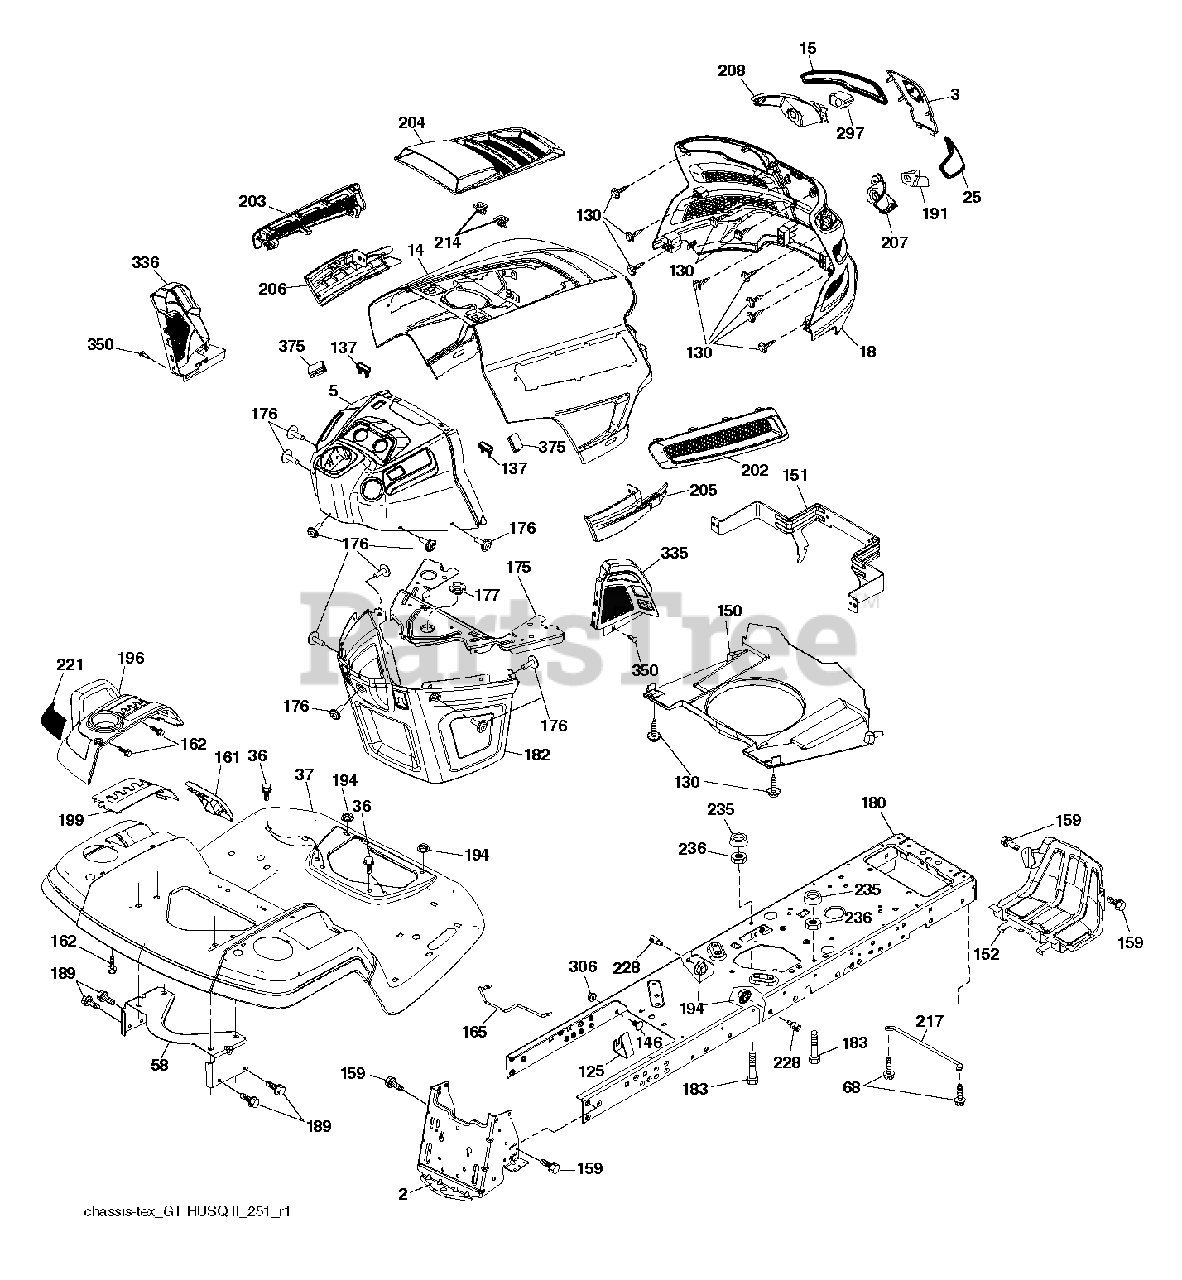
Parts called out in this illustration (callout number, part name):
2	DRAWBAR.STGT
3	APPLIQUE.SUBASM.GT.HUSQ.II
5	DASH.UPR.GT2.SRV.MIND.PTO
14	HOOD.ASM.HUSQVARNA.GT.TEX.ORAN
15	LENS.HEADLIGHT.LH.GTII.2011
18	GRILLE SUBASM.GT.II.LOW.HDLGHT
25	LENS.HEADLIGHT.RH.GTII.2011
36	SCREW 5/16"
37	FENDER.PNT.TX.GT.CH/FW/DL.HUSQ
58	BRKT.SUPPORT.FNDR/TANK
68	SCR 5/16-18 X 1/2 SELFTAP ZN
125	CLIP.FUEL.LINE
130	SCREW.#10 X 0.750.BOS
137	BUMPER DASH
146	BOLT.RDHD.SHT.SQNK.3/8-16X5/8
150	AIR.DUCT.GTV.BLACK
151	BRACKET.PIVOT.HOOD.GT.HUSQ.II
152	SHIELD.BROWNING.PNT.GT.V2
159	SCREW, 3/8-16X3/4
161	CONSOLE.WINDOW.FUEL.HUSQ.GT
162	SCREW.HI-LO.CONSOLE
165	SUPPORT.TANK.REAR.B/TE
175	PLATE.CROSSMEMBER.HUSQ
176	SCREW.#10-24X5/8.RN.QU
177	BUSHING STEERING
180	CHASSIS.LT/GT.BOLTED
182	DASH LOWER.HUSQ.PRED NO CRUISE
183	BOLT.5/16-18X1-1/4 FULL THD
189	SCREW
191	INSERT.REFLECTIVE.RH.HUSQ.GTII
194	NUT LOCK HEX FLANGE 5/16-18
196	SUBASM.CONSOLE.HUSQ.GT.DECKLFT
199	PLATE.DECK.LIFT.HUSQVARNA.GT
202	VENT.SIDE.RH.GT.HUSQ.II.
203	VENT.SIDE.LH.GT.HUSQ.II.498
204	VENT.TOP.HUSQ.GT2
205	SIDE.TRIM.RH.GT.HUSQ.II
206	SIDE.TRIM.LH.GT.HUSQ.II.GRAY
207	HEADLIGHT.CUP.BEZEL.HUS.GT2.RH
208	HEADLIGHT.CUP.BEZEL.HUS.GT2.LH
214	CLIP.RETAINER.TINNER.
217	ROD.PIVOT.HOOD
221	REFLECTOR.LH.TEX GT HU
228	STUD.FASTNER.W/ANTI-ROTATE
235	SPACER FENDER
236	NUT.CENTERLOCK.5/16-
297	INSERT.REFLECTIVE.LH.HUSQ.GTII
306	NUT LOCK FLG 3/8-16 UNC
335	COVER.LOWER.DASH.RH.BLACK
336	COVER-LH.LOWER.DASH.GT2.BLACK
350	CLIP.X-MAS.TREE
375	BUMPER CLIP-ON. DASH 1"
